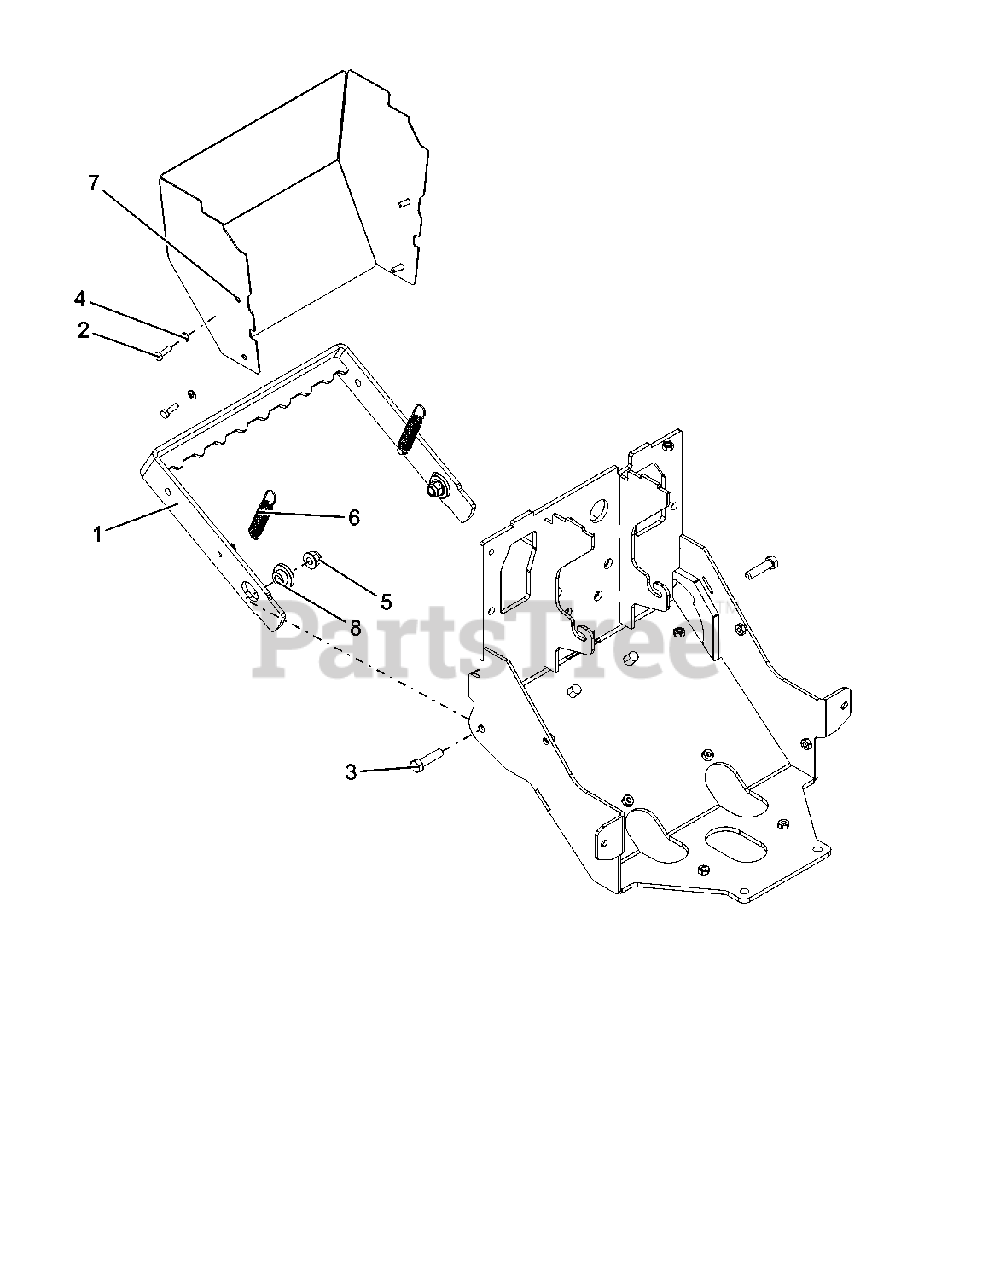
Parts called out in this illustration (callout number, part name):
1	WLDMT, STAND SUPPORT-RED
2	BLT, HEX M6-1X20 GR8.8 ZC120
3	BLT, HEX M10-1.5X40 GR8.8 ZC120
4	WSHR-LK .25X.062 REG YWZC
5	NUT, LK-NYL-FLG M10-1.5 GR8.8 ZC120
6	SPRG, EXTENSION .063 X .653 X 2.755
7	COVER, STEERING-RED
8	BSHG, STEP .413X.776X1.25X.413
